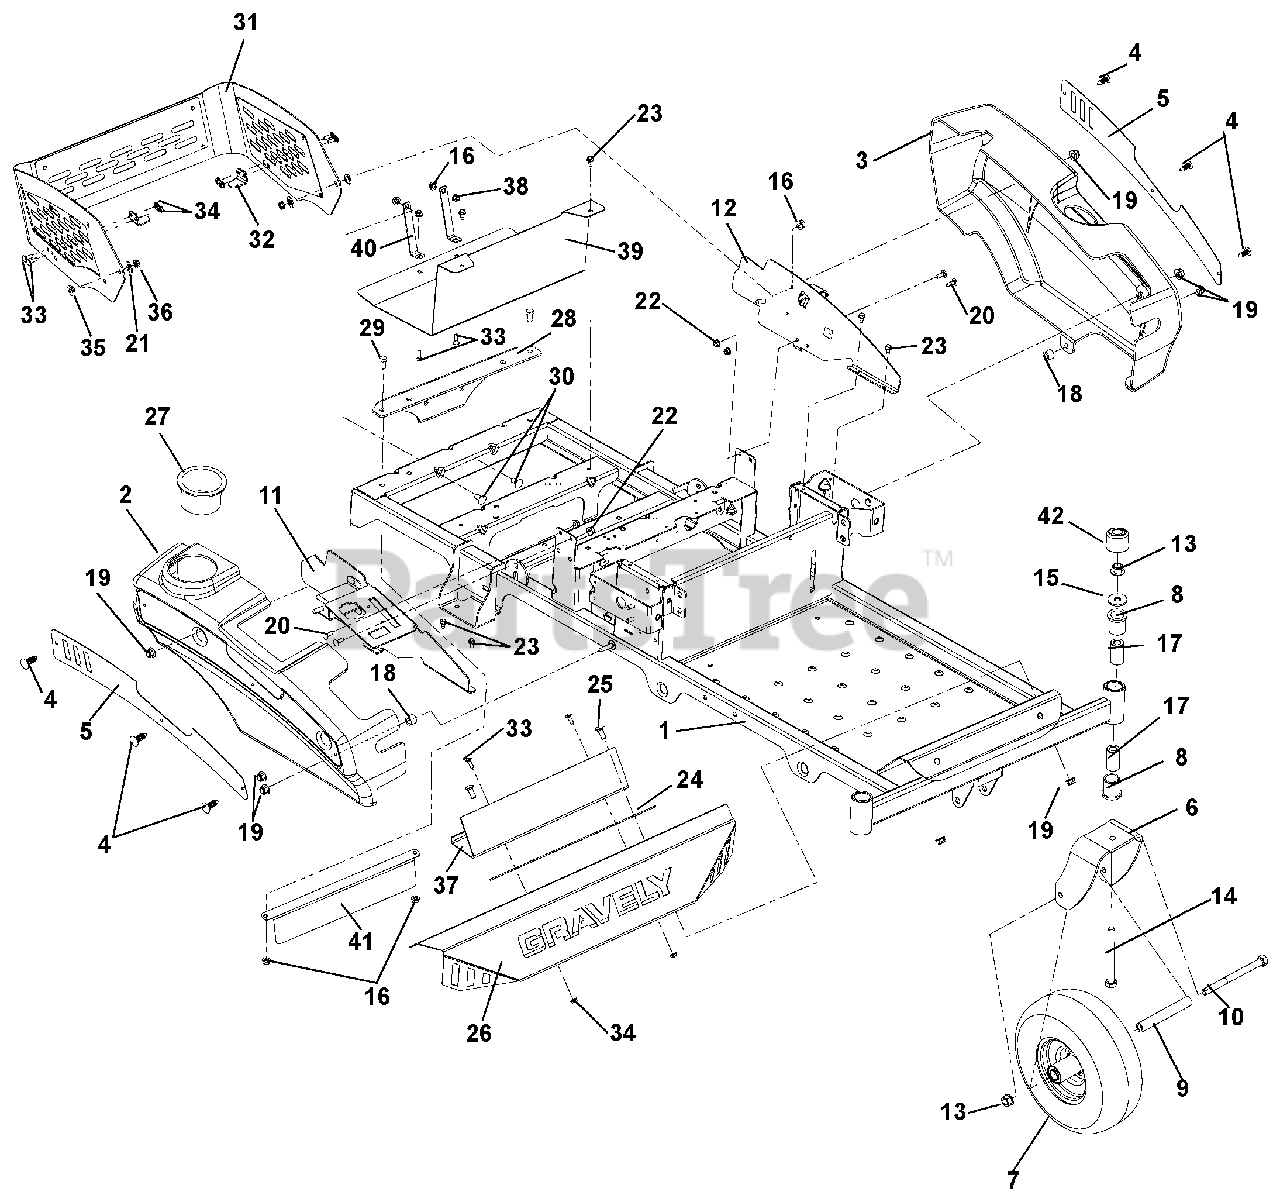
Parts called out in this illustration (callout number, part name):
1	Weldment, Frame
2	Fender, Right Hand
3	Fender, Left Hand
4	Rivet, Nylon
5	Plate, Fender
6	Fork, Caster
7	Tire/Wheel Assembly, 11 x 4-5
8	Bushing, Flange 1.00 x 1.25 x 1.50 x 1.50
9	Spacer, Wheel
10	Bolt, Hex .50-13 x 6.50
11	Weldment, Fender Mount Right Hand
12	Weldment, Fender Mount Left Hand
13	Nut, Locking, Top, Flange .50-13
14	Bolt, Hex .50-13 x 5.00
15	Washer, Flat Steel .511 x 1.441 x .125
16	Nut, Locking, Top, Flange .38-16 (915328)
17	Spacer, Caster
18	Bushing, Sleeve .391 x .688 x .52
19	Nut, .31-18 Nyloc Flange
20	Bolt, Round Head Square Neck .25-20 x .75
21	Washer, Flat, Nylon .52 x 1.00 x .08
22	Nut, .25-20 Nyloc Flange
23	Screw, Tapping .25-20 x .50 Hex Washer Head Thread
24	Grip, Adhesive (1" x 16" BLK)
25	Bolt, Round Head Square Neck .31-18 x .75
26	Foot Rest
27	Cupholder
28	Plate, BBZ Hitch Kit Plate (915328)
29	Bolt, Hex .38-16 x 1.00
30	Bolt, Round Head Square Neck .31-16 x .75
31	Assembly, Engine Wrap
32	Bracket, Engine Wrap Foot
33	Bolt, Round Head Square Neck .25-20 x .50
34	Nut, Center Lock Flange .25-20
35	Bushing, Flange .325 x .499 x .3 x .875
36	Nut, Center Lock Flange .31-18
37	Plate, Back Foot Rest
38	Nut, Locking Top Flange .25-20
39	Guard, Heat Shield (ZT)
40	Strap, Heat Shield (ZT)
41	Guard, Hot Surface (ZT)
42	Cap, Dust
